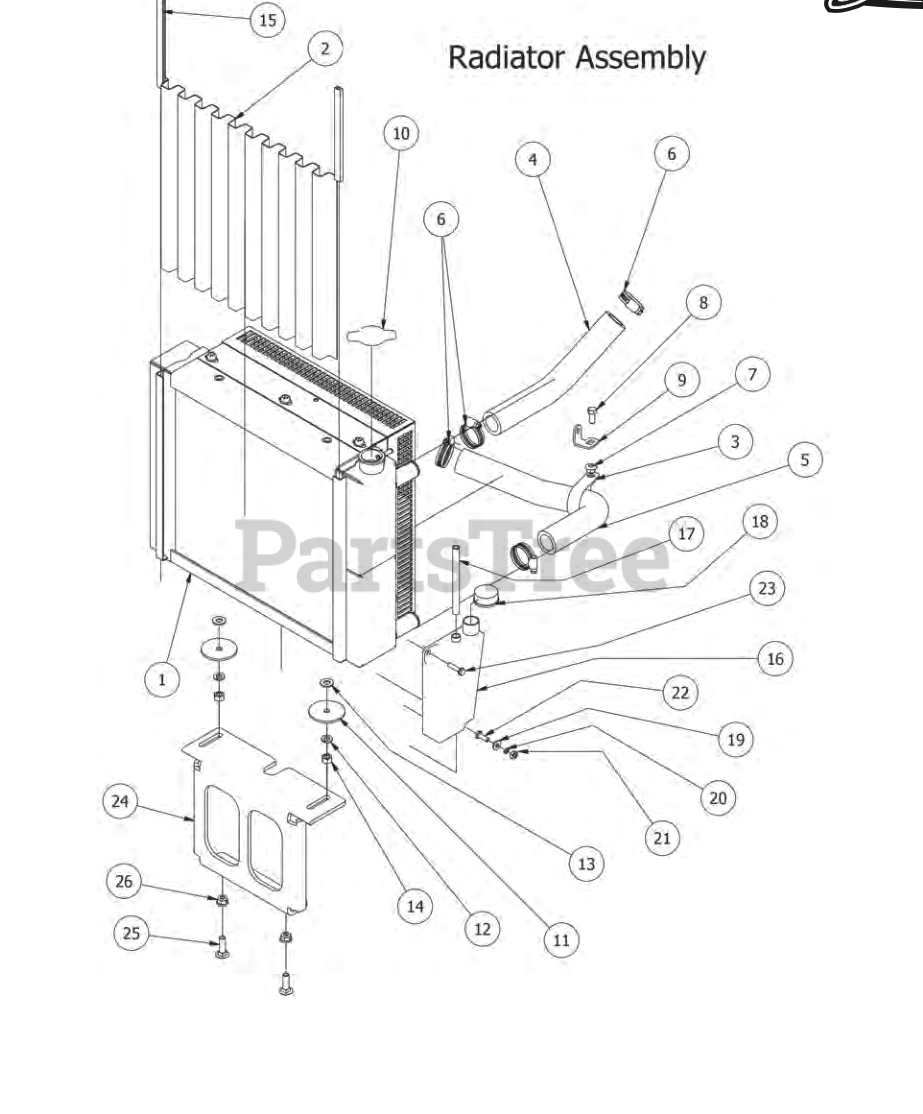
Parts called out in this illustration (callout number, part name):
1	Radiator- Diesel
2	Radiator Screen-Diesel
3	Diesel Clamp 1 3/4" Vinyl
4	Top Radiator Hose for Diesel
5	Bottom Radiator Hose for Diesel
6	1 1/8" Hose Clamp
7	5/16" Nylock Flange Nut
8	5/16" x 3/4" Hex Bolt
9	Diesel Radiator Hose Clamp Bracket
10	Radiator cap
11	3/8 x 2-1/4 OD Fibre Washer
12	3/8" Lock Washer
13	3/8" Flat Washer
14	3/8" Hex Nut
15	Rubber Trim
16	overflow Reservoir- 28/35Hp Diesel
17	5/16 Clear Hose
18	Reservoir Tank Cap-Overflow
19	1/4" Flat Washer
20	1/4" Lock Washer
21	1/4" Hex Nut
22	1/4" x 3/4" Hex Bolt
23	1/4 x 1 Hex Head tek screw
24	Compact Diesel Radiator Support (bolt on)
25	3/8" x 11/4" Carriage Bolt
26	3/8" Nylock Flange Nut
